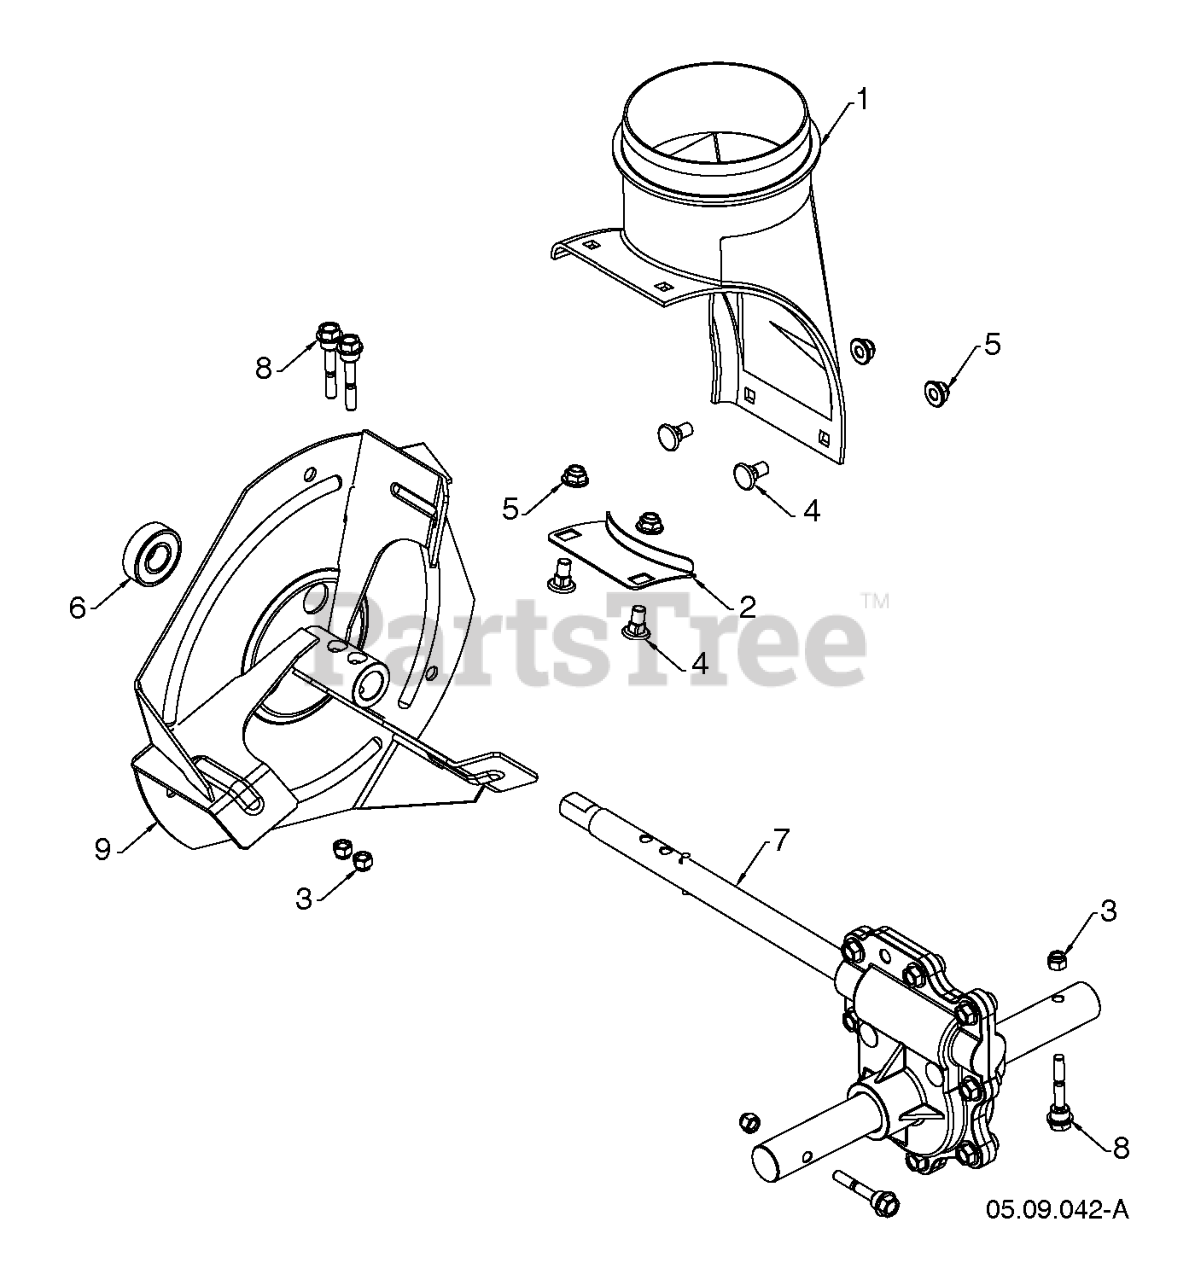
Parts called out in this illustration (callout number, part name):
1	CHUTE.DISCHARGE.BASE
3	NUT HEXAGON 1/4-20 ST ZPB
4	BOLT CARR WAFER BLK 5_16-18 X
5	NUT HEX FLG NYLOCK BLK 5_16-1
7	TRANSMISSION.GEARBOX.ALUM.DD
8	BOLT SHEAR HX HD 1/4-20 CLEAR
9	IMPELLER.STEEL.SNOW.BLACK
